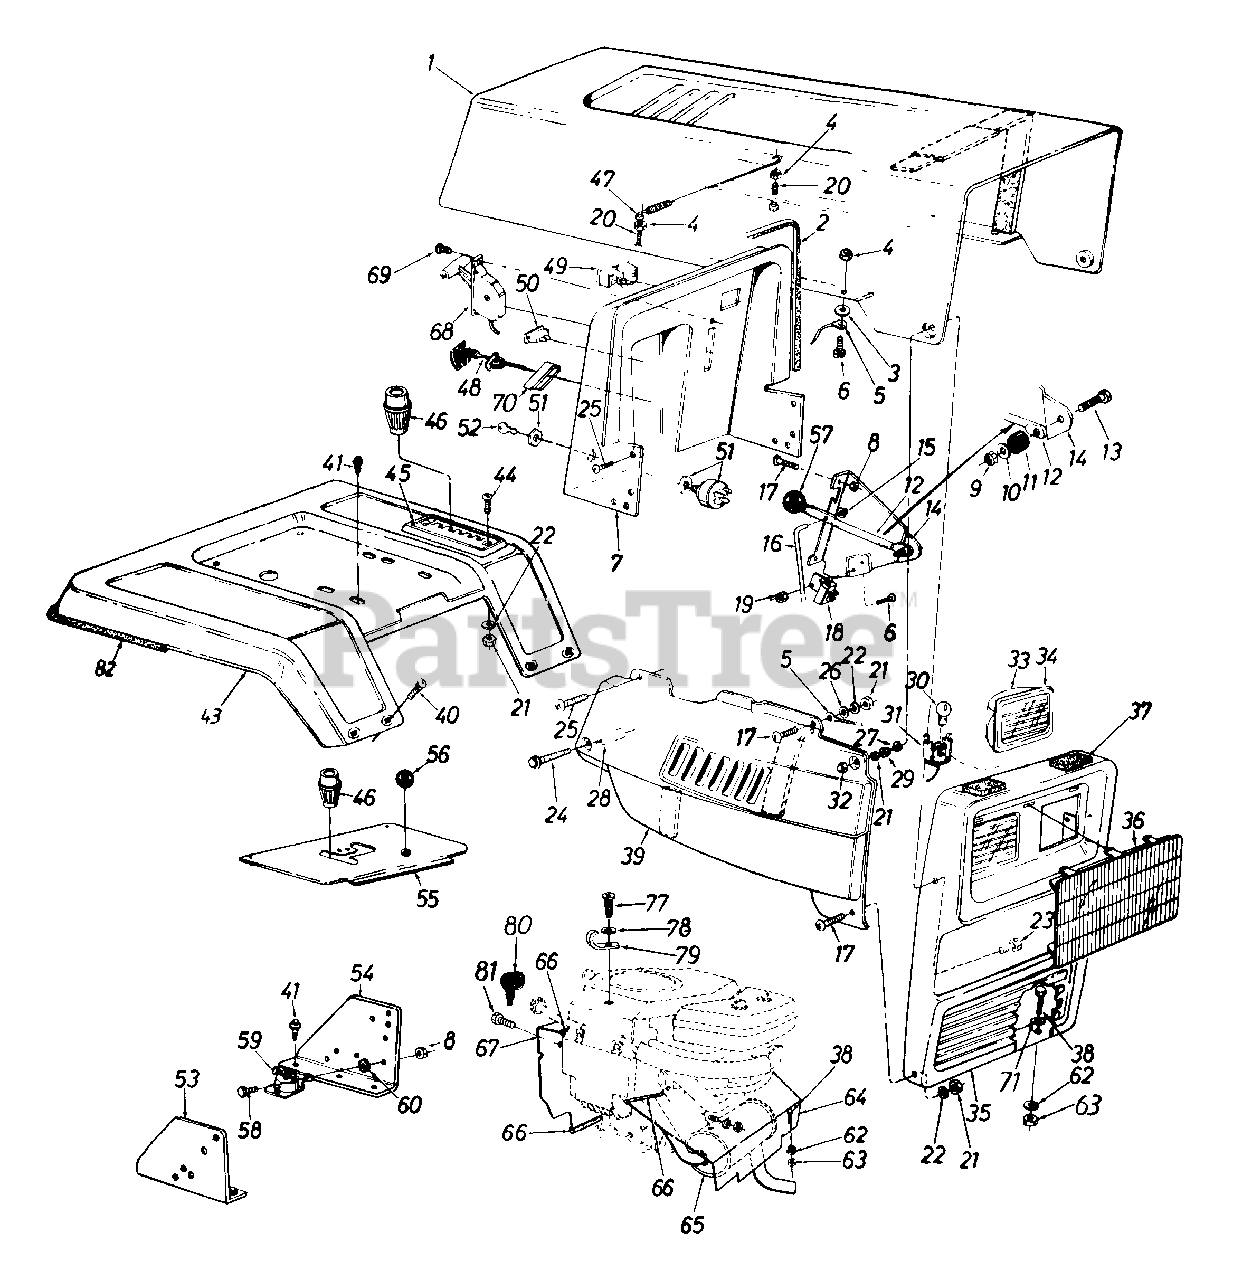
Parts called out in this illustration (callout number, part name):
3	Fl-Wash. .20" I.D. x .41" O.D.
4	Hex Sems Nut #10-24 Thd.
5	Hood Stop
6	Truss Mach. Scr. #10-24 x .5" Lg.
9	Hex L-Nut 1/4-20 Thd.
10	Fl-Wash. .281" I.D. x.73" O.D.
11	Rubber Washer
12	PTO Lever
13	Hex Bolt 1/4-20 x 1.25" Lg.
14	Deck Clutch Control Brkt.
15	Push Cap
16	Deck Control Rod
17	Truss Mach. Scr. 1/4-20 x .5" Lg.
18	Safety Switch
19	Hex Sems Nut #10-24 Thd.
20	Hex Bolt 10-24 x 1.0" Lg.
21	Hex Nut 1/4-20 Thd.
22	L-Wash. 1/4" I.D.
23	Hex Bolt 1/4-20 x .88" Lg.
24	Hex Wash. TT-Tap Scr. 1/4-20 x 1.75" Lg.
25	Hex TT-Tap Scr. 1/4-20 x .75" Lg.
26	Fl-Wash. .25" I.D. x .62"
27	Spr. Wash. .39" I.D. x .62"
28	Spacer .26" I.D. x .375"
29	Shld. Spacer .375" Dia. x .125" Lg.
30	Lamp
31	Socket
32	Acorn Nut 1/4-20 Thd.
33	Headlight Housing
34	Headlight Lens
37	Foam Strip
38	Hex Bolt 5/16-18 x .75" Lg.
41	Hex Wash. AB-Tap Scr. 5/16 x .75" Lg.
45	6-Speed Selector Plate
46	Shift Knob
47	Hood Spring
48	Choke Control 46" Lg.
49	Ammeter
50	Light Switch
51	Ignition Switch
52	Ignition Key
56	Ball Knob
57	Knob - Blade Clutch
58	Hex Bolt 1/4-20 x 5" Lg.
59	Solenoid
60	Ext. L-Wash. 1/4" I.D.
62	L-Wash. 5/16" I.D.
63	Hex Nut 5/16-18 Thd.
64	Front Heat Shield
65	Muffler
66	Trim Strip 12" Lg.
67	Rear Baffle
68	Throttle Control Box Ass'y.
69	Truss Mach. AB-Tap Scr. #10 x .5" Lg.
70	Retainer Clip
71	Fl-Wash. .344" I.D. x 1" O.D. (Hdn.)
77	Truss Mach. B-Tap Scr #10 x 5 Lg.
78	Fl-Wash. .188" I.D. x .438" O.D.
79	Clamp
81	Hex Wash Hd. TT-Tap Scr. 1/4-20 x .5" Lg.
82	Trim Strip 81" Lg.
